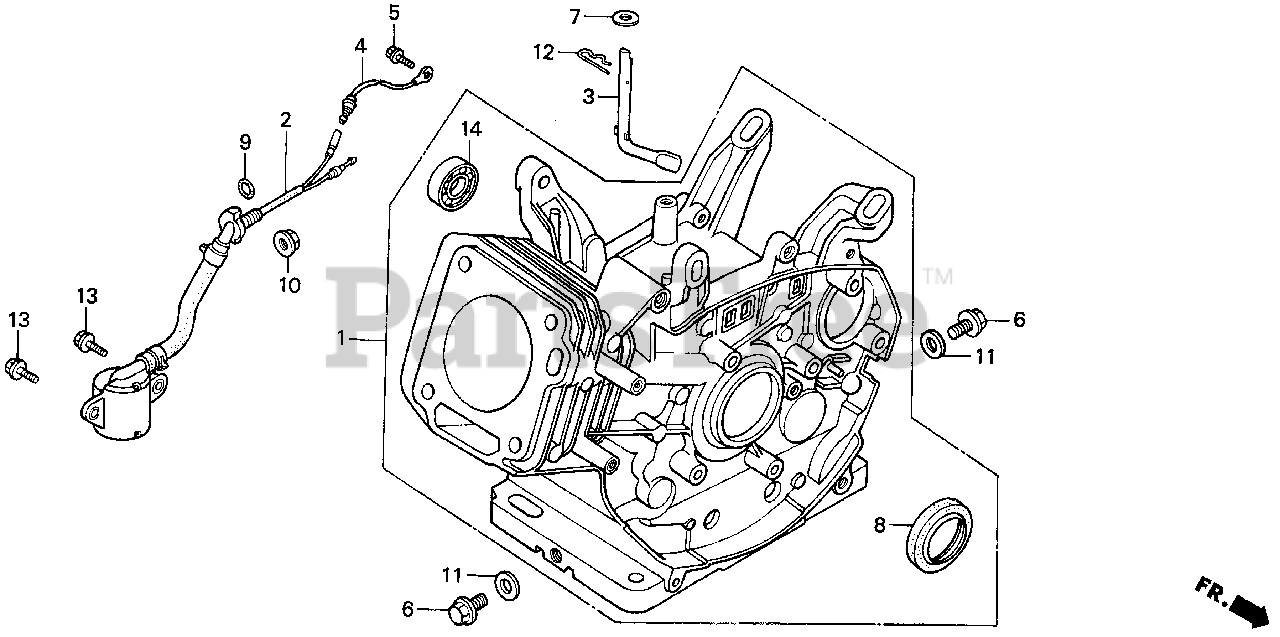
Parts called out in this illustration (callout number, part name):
1	CYLINDER ASSY. (BALANCER+ALERT)
2	SWITCH ASSY., OIL LEVEL
3	SHAFT, GOVERNOR ARM
4	SUB-HARNESS
5	BOLT, FLANGE (6X12) (CT200)
6	BOLT, DRAIN PLUG
7	WASHER (8.2X17X0.8)
8	OIL SEAL (30X46X8)
9	O-RING (13.5X1.5) (ARAI)
10	NUT, FLANGE (10MM)
11	WASHER, DRAIN PLUG (12MM)
12	PIN, LOCK (8MM)
12	PIN, LOCK (10MM)
13	BOLT, FLANGE (6X12)
14	BEARING, RADIAL BALL (6202)
